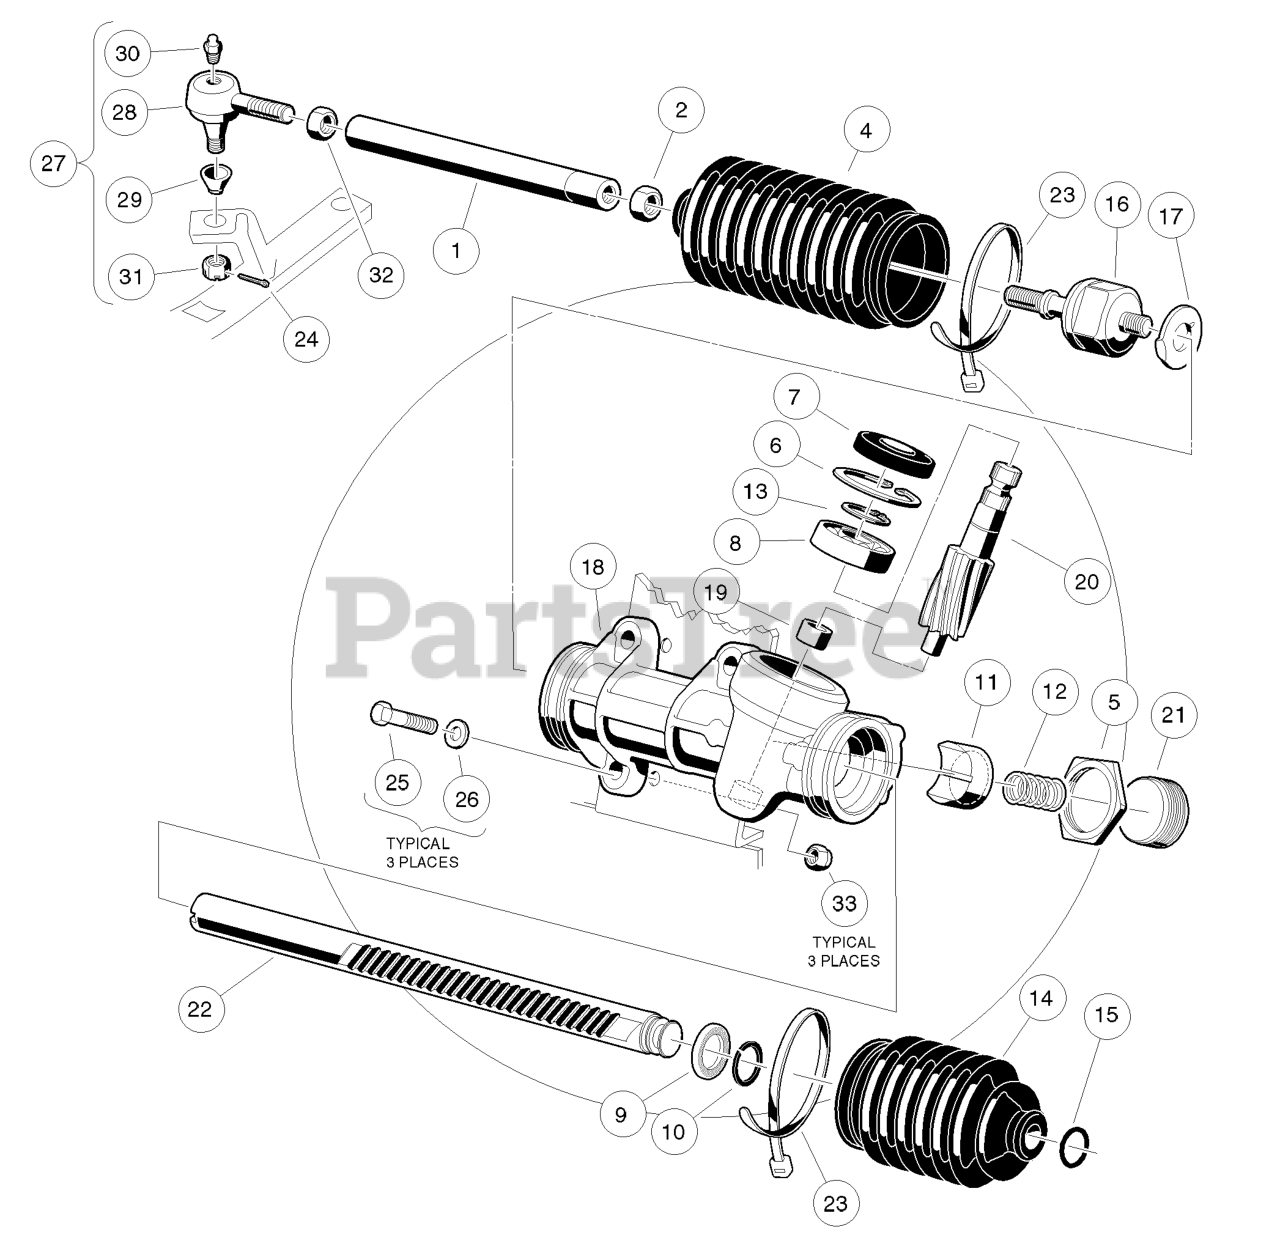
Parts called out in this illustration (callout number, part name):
1	DRAG LINK RACK & PINION
2	12MM HEX NUT
3	ASM, STEERING RACK, 3.13
4	BELLOWS, LONG
5	RACK SCREW LOCKNUT
7	SEAL, STEERING PINION DUST
8	BEARING BALL
9	STOP WASHER
10	STOP RING C - TYPE
11	SUPPORT YOKE
12	RACK GUIDE PRESSURE SPRING
13	C-TYPE STOP RING
14	BELLOWS, SHORT
15	DUST SEAL RETAINING RING
16	INNER BALL JOINT ASM
17	WASHER, TAB
18	Box, Steering Gear
19	Bearing, Lower Pinion
20	Pinion, Steering
21	Screw, Rack Guide
22	Rack, Steering
23	TIE WRAP, 8" NYLON
24	PIN,CUT COTTER
25	SCREW, 3/8-16 X 1.5 HX HD CAP
26	WASHER, 3/8 FLAT
27	BALL JOINT, LH
28	Socket, LH Vertical
29	SEAL, VERTICAL SOCKET DUST
30	FITTING, 1/4-28 THRD FRM GREAS
31	NUT, 3/8-24 UNF HEX THICK SLOT
32	NUT, 1/2-20 HEX
33	LOCKNUT, 3/8-16 HEX
